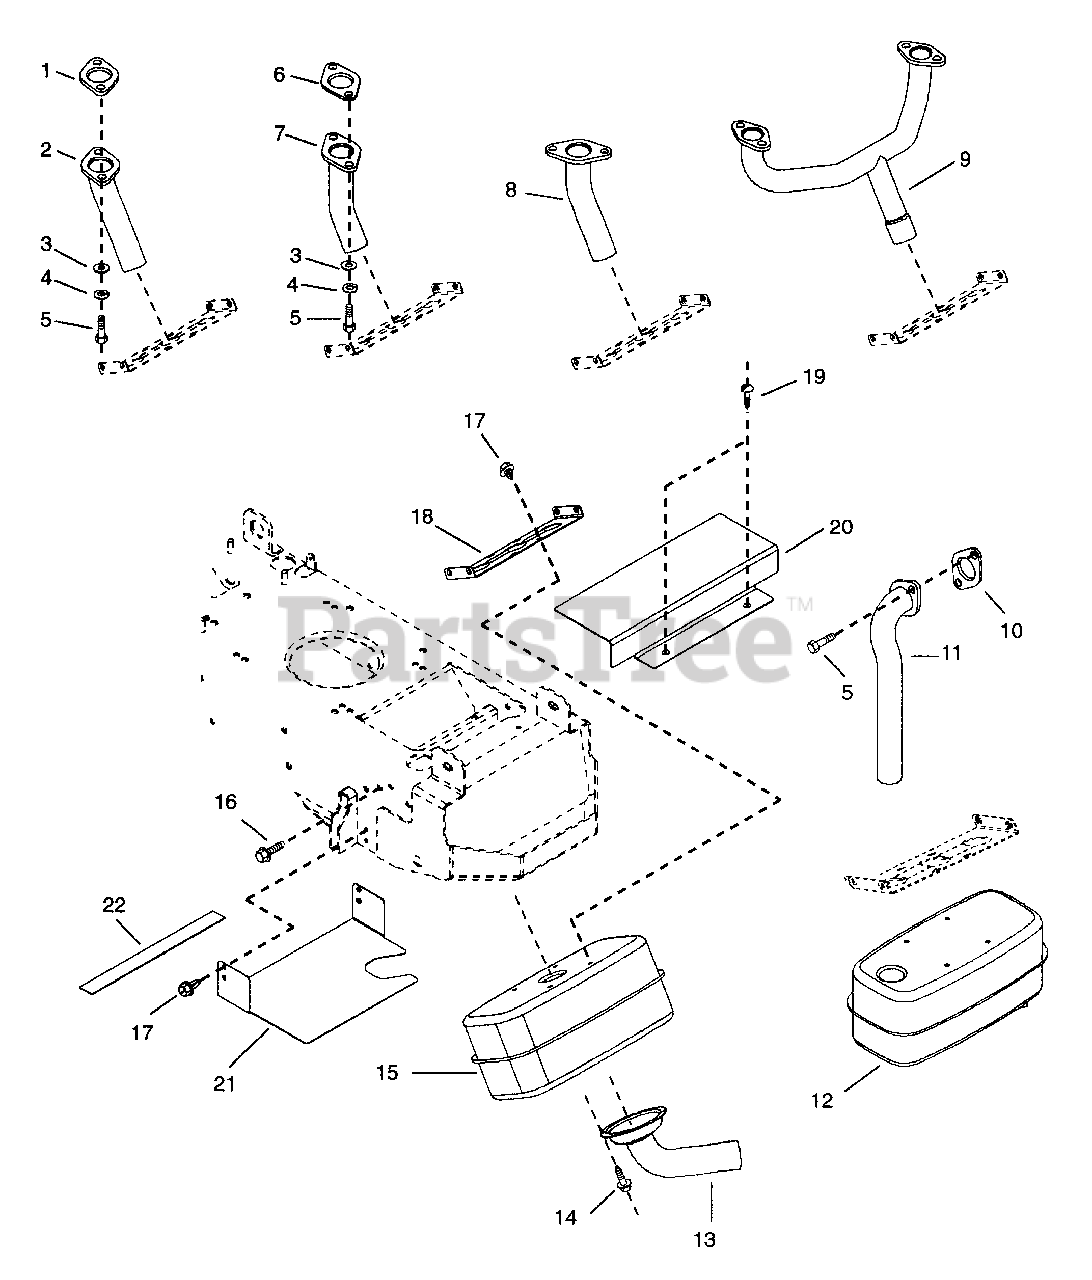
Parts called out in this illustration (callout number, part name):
1	GASKET- 12.5/13 TEC (#35-414)
2	TUBE - EXHAUST WELD. 13 HP
3	WSHR-FL-STL .323X.625X.062 PL
4	WSHR-LK .313X.078 PL MED
5	SCR-CAP .31-18X.75 S/HD
6	GASKET:15-16.5HP TEC (#35-438)
7	TUBE - EXHAUST WELD 15-16.5 HP
8	PIPE - EXHAUST
9	PIPE - EXHAUST TWIN B&S
10	GASKET B&S#272293
11	PIPE - EXHAUST
12	MUFFLER W/DEFLECTOR
13	DEFLECTOR - EXHAUST
14	SCR-TAP 8-32X.38 SL HWH PL 23
15	MUFFLER - EXHAUST
16	SCR-TAP .312-18X.50 HWH PL TR
17	SCR-TAP 12-24X.50 HWH PL TR
18	BRACKET - MUFFLER
19	SCR-TAP .312-18X.50 PL F
20	SHIELD - HEAT
21	SHIELD - HEAT
22	HEAT SHIELD- FABRIC 1X10.75
